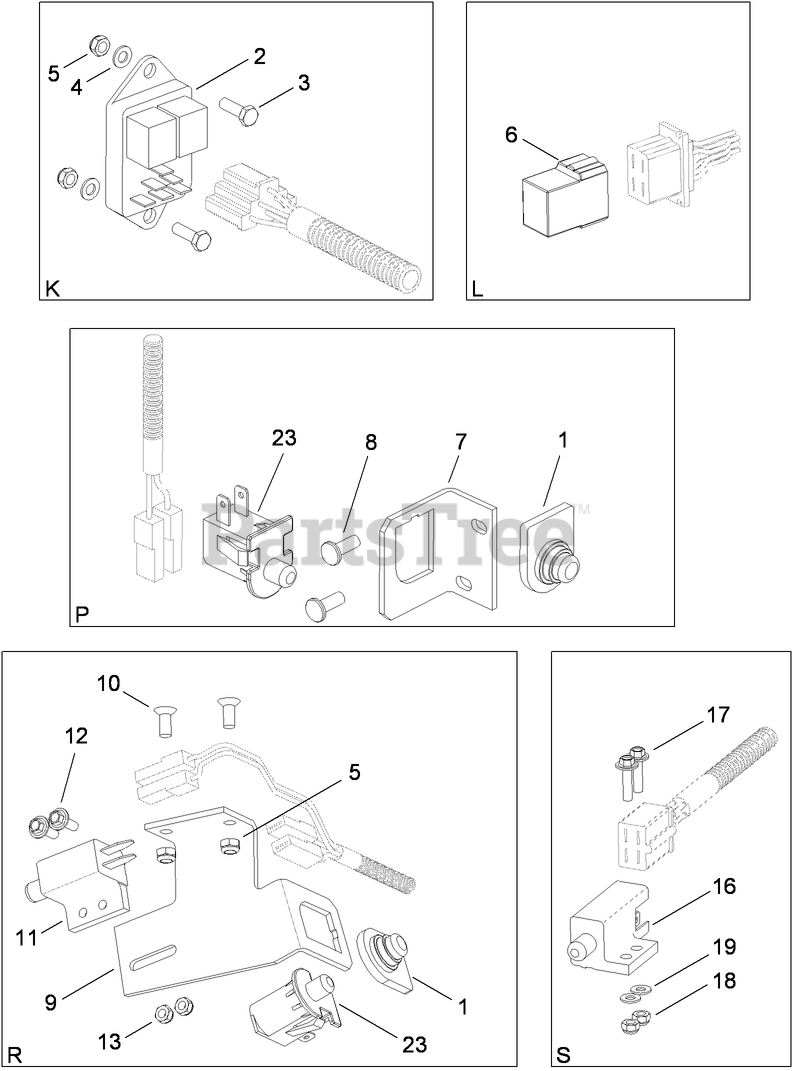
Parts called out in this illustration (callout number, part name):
1	COVER-PROTECTIVE
2	MODULE-CLUTCH
3	SCREW-HH
4	WASHER
5	NUT-LOCK
6	CIRCUIT-MEMORY
7	HOLDER-SWITCH
9	HOLDER-SWITCH
11	SWITCH-POLE, SINGLE
13	NUT-HEX
16	Switch-Delta
18	NUT-LOCK
19	WASHER
23	SWITCH-DELTA
